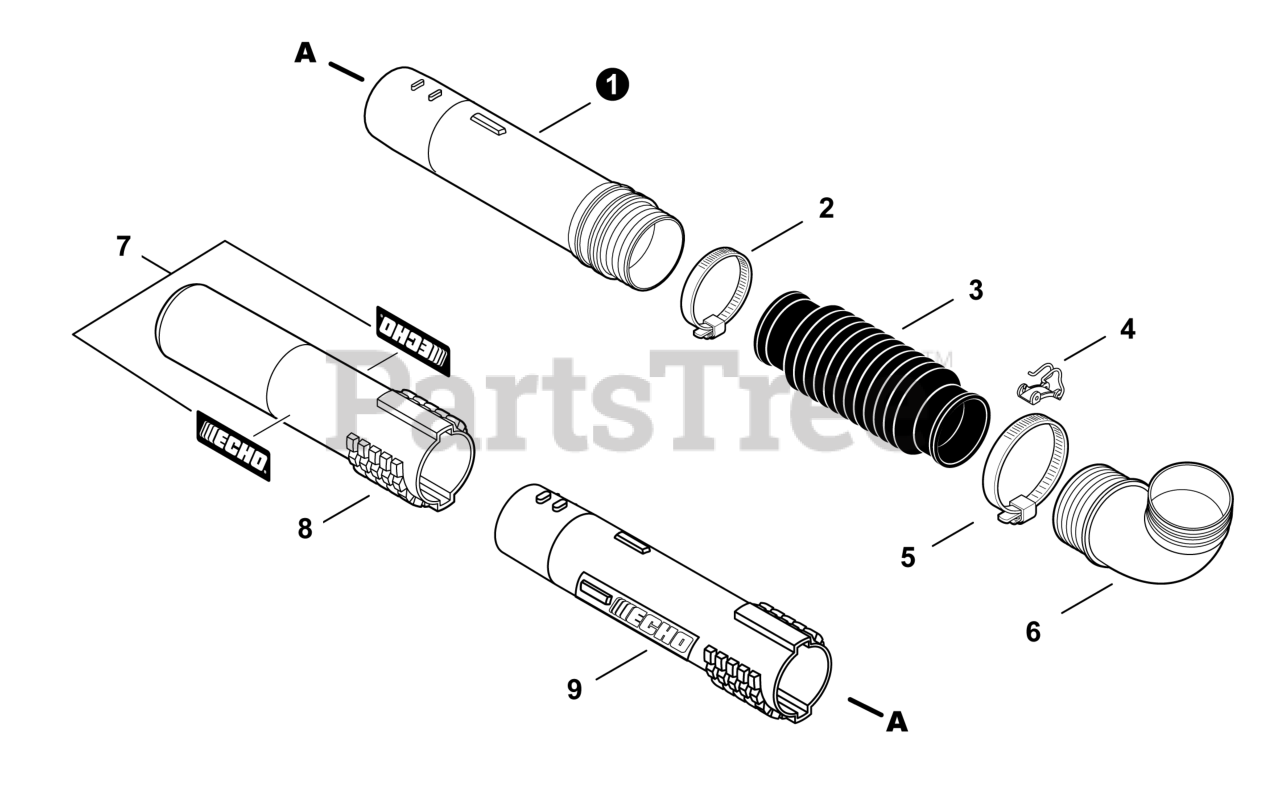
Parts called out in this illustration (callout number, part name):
1	TUBE, BLOWER - SWIVEL
2	CLAMP 58.7 MM / 82.5 MM
3	TUBE, BLOWER - FLEXIBLE
4	CLIP, CABLE
5	CLAMP - BAND
6	TUBE, BLOWER - ELBOW
7	LABEL - ECHO
8	TUBE, BLOWER - NOZZLE
9	TUBE, BLOWER - STRAIGHT
